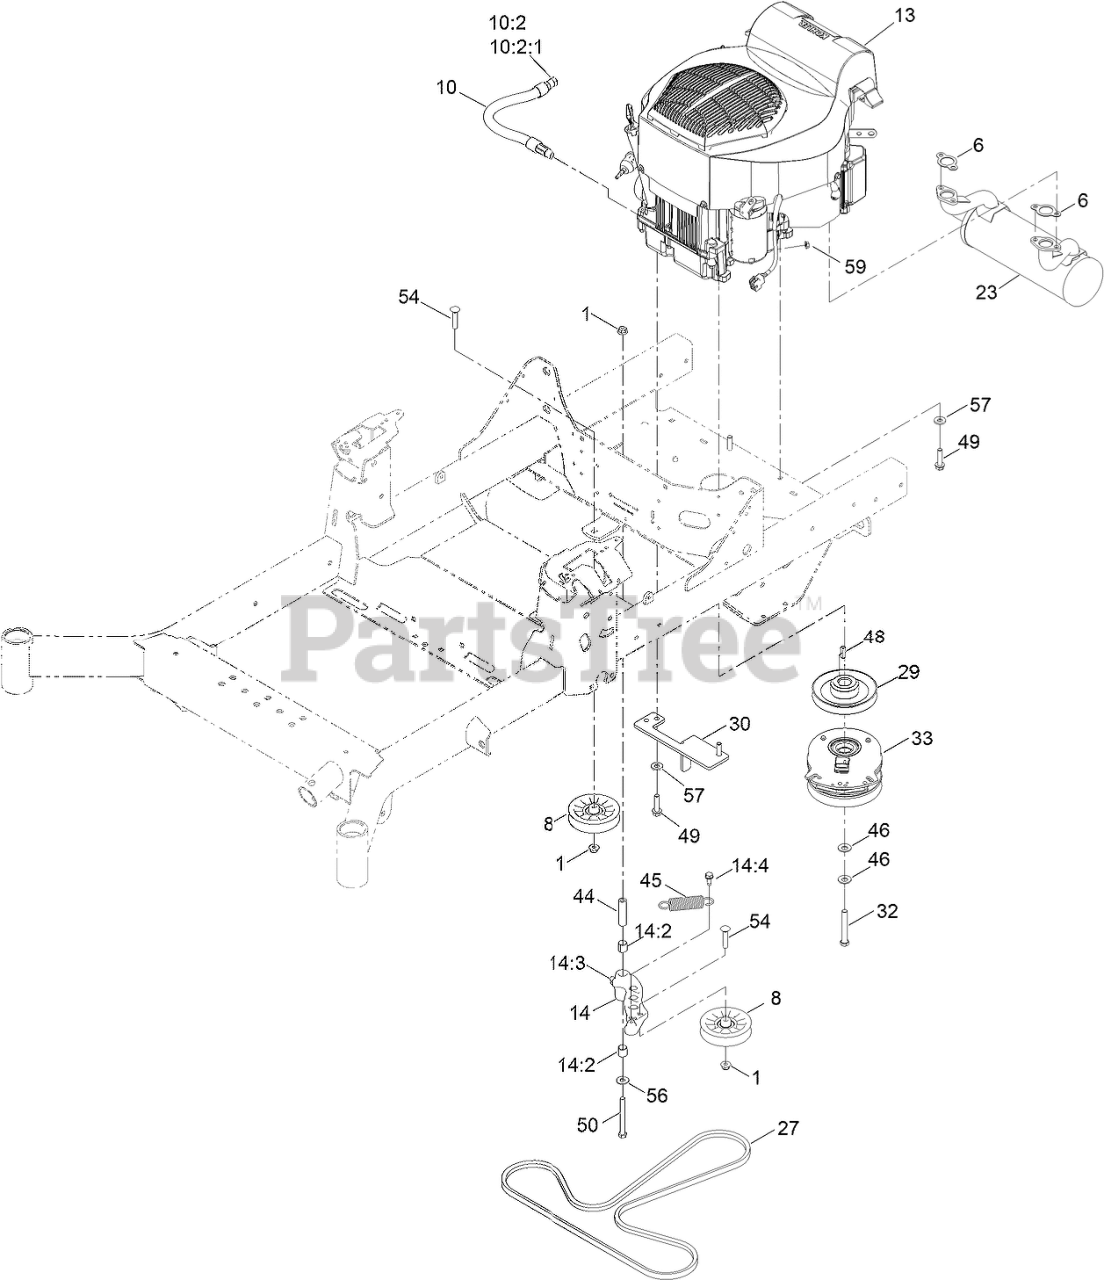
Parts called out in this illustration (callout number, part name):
1	NUT-HF, NI
8	PULLEY-FLAT IDLER
10	OIL DRAIN HOSE ASM
10:2	PLUG-HH
10:2:1	O-RING
14	IDLER ARM ASM
14:2	SLEEVE-BEARING
14:3	FITTING-GREASE, 90 DEG
14:4	SCREW-THD ROLL, HWH
23	MUFFLER-KOHLER AES
27	BELT-V
29	SHEAVE-ENGINE
30	ANCHOR-CLUTCH
32	SCREW-HH W/LOCTITE
33	CLUTCH-PTO
44	BUSHING-PIVOT, IDLER
45	SPRING-EXTENSION
46	WASHER-SPRING
49	SCREW-HWH
50	SCREW-HH
54	SCREW-CARR
56	WASHER-FLAT
57	WASHER-BELLEVILLE
59	NUT-HF
